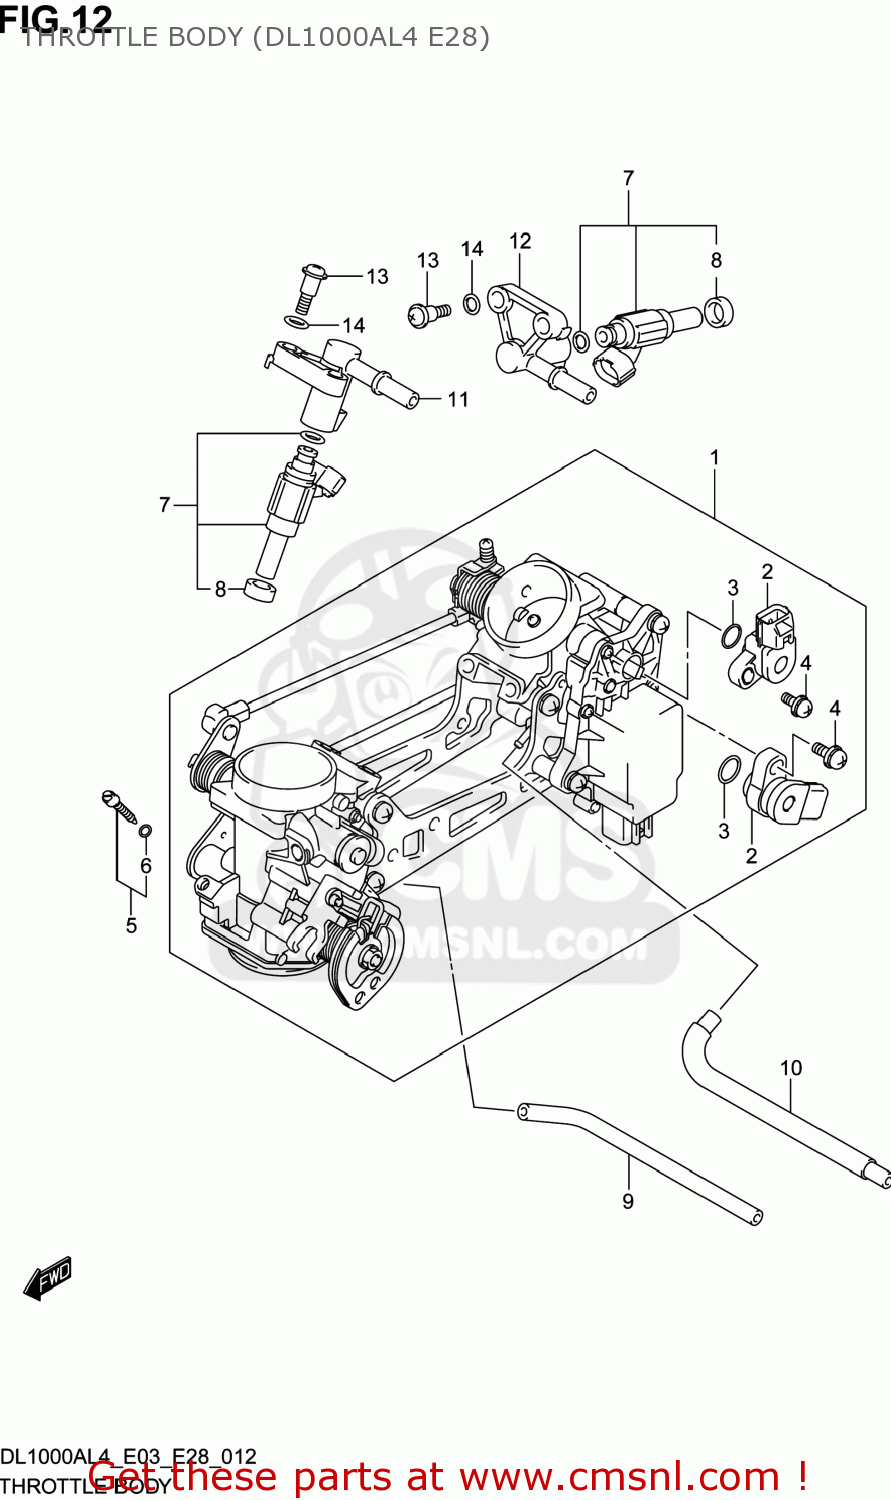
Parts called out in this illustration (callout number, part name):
1	BODY ASSY,THROTTLE
2	SENSOR
3	O RING
4	SCREW
5	ADJUSTER,BAS
6	O RING
7	INJECTOR ASSY
8	SEAL
9	HOSE
10	HOSE
11	DELIVERY PIPE
12	DELIVERY PIPE
13	SCREW
14	PACKING (NAS)
